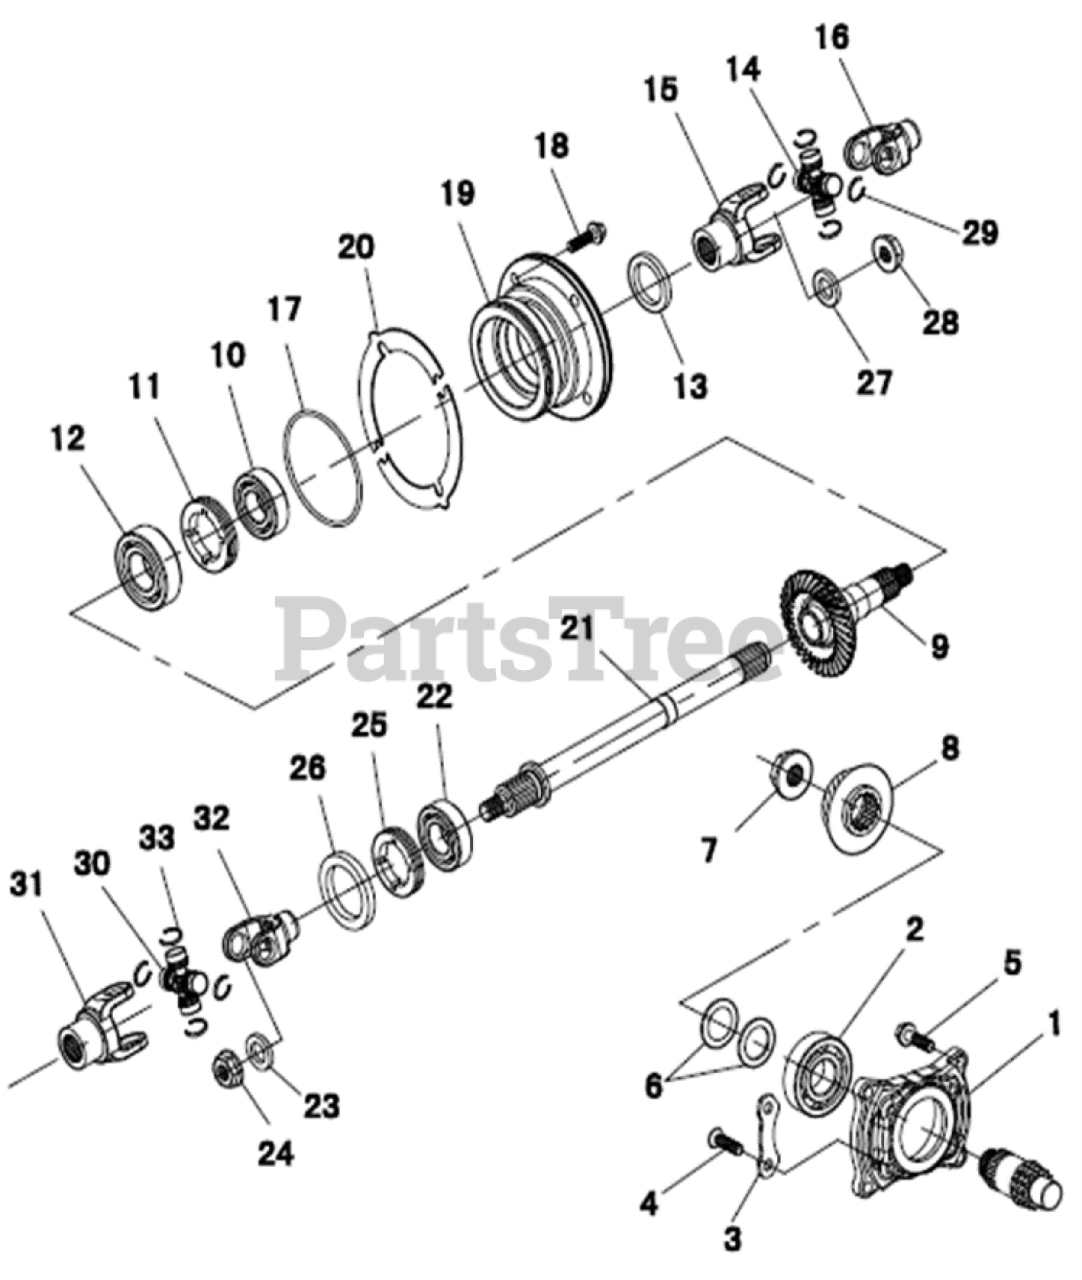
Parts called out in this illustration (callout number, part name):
1	X Shaft Bearing Block
2	Bearing 6305
3	Press Plate,X Shaft Bearing Block
4	Cross recessed countersunk head screw M8X25
5	Hexagon flange bolts M8X30
6	Washer 26X38X0.4
7	Hexagon Flange Nut M22X1
8	Driving bevel gear
9	Driven bevel gear
10	Bearing 63/22
11	External thread nut M60X1.5
12	Bearing 6207
13	Oil Seal 30X46X8
14	Knuckle Centre ?22?
15	U-joint A(22?
16	U-joint B(22?
17	O-Ring 88X2.8
18	Hexagon head bolt and plain washer assemblies M8X30
19	Y Shaft Bearing Block
20	Washer 0.1,Bevel Gear
20	Washer 0.2,Bevel Gear
20	Washer 0.3,Bevel Gear
20	Washer 0.4,Bevel Gear
20	Washer 0.5,Bevel Gear
20	Washer 0.6,Bevel Gear
21	Y Driveshaft
22	Bearing 6205
23	Washer 14.5X32X5
24	Self-locking Nut M14X1.5
25	External thread nut M55
26	Oil Seal 44X60X7
27	Washer 16.5X28X4
28	Self-locking Nut M16X1.5
29	Grip Ring 22
30	Knuckle Centre ?22?
31	U-joint B(22?
32	U-joint A(22?
33	Grip Ring 22
